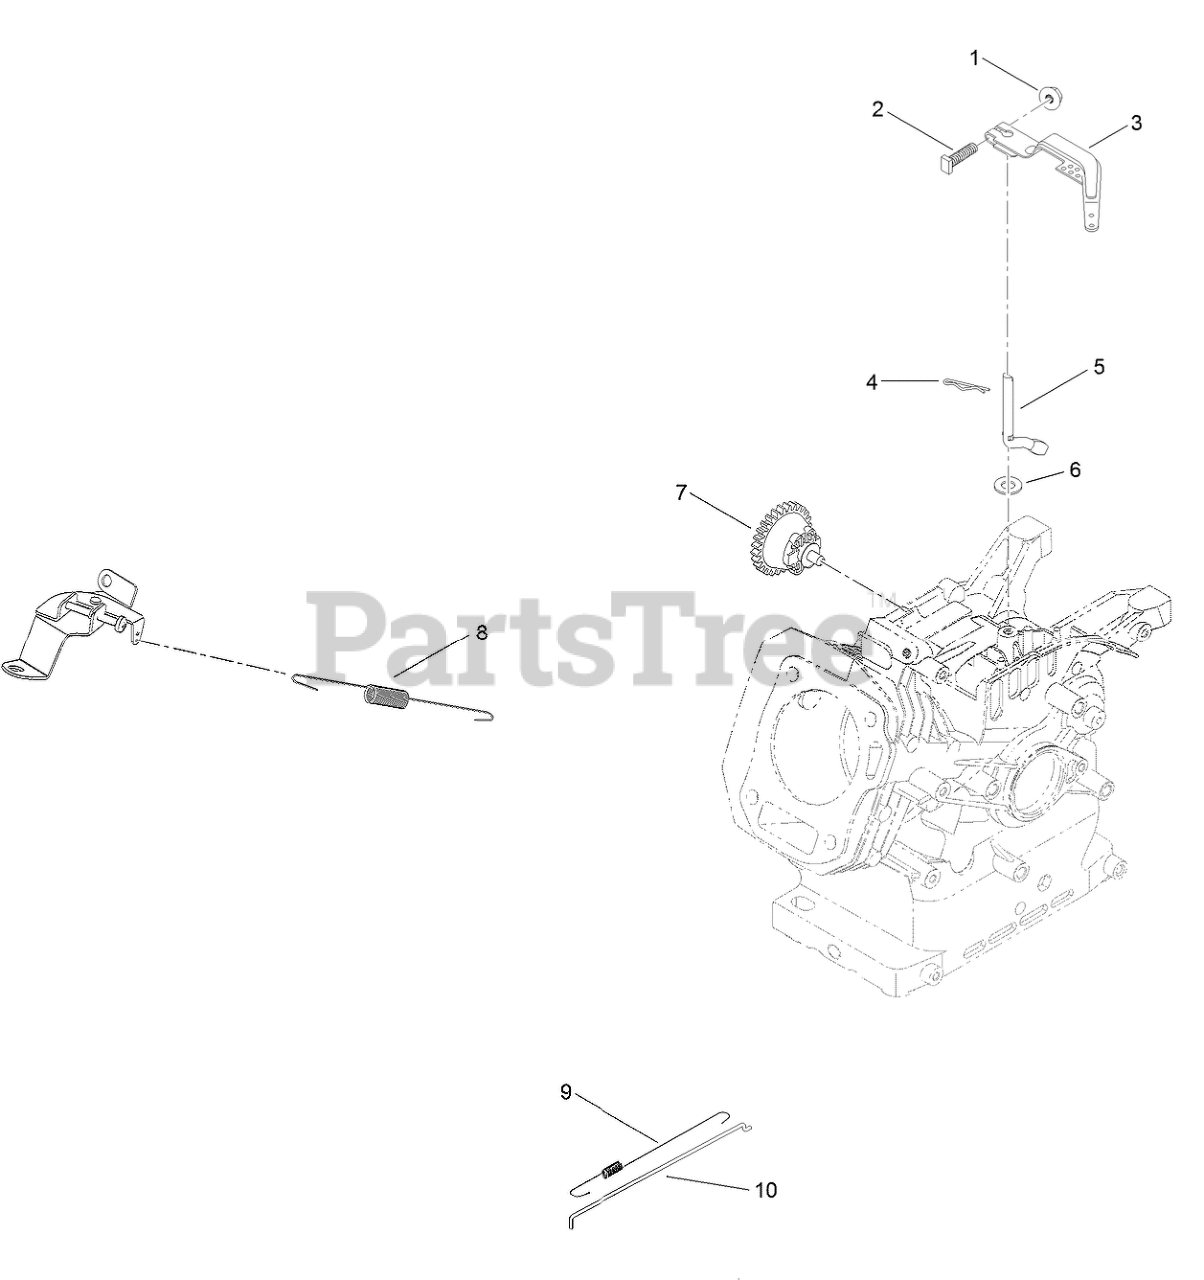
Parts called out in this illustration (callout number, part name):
1	NUT-FLANGE
2	BOLT-ARM, GOVERNOR
3	ARM-GOVERNOR
4	PIN-HAIR
5	SHAFT-GOVERNOR
6	WASHER-PLAIN
7	GOVERNOR GEAR ASM
8	SPRING-GOVERNOR
9	SPRING-RETURN, THROTTLE
10	ROD-GOVERNOR
